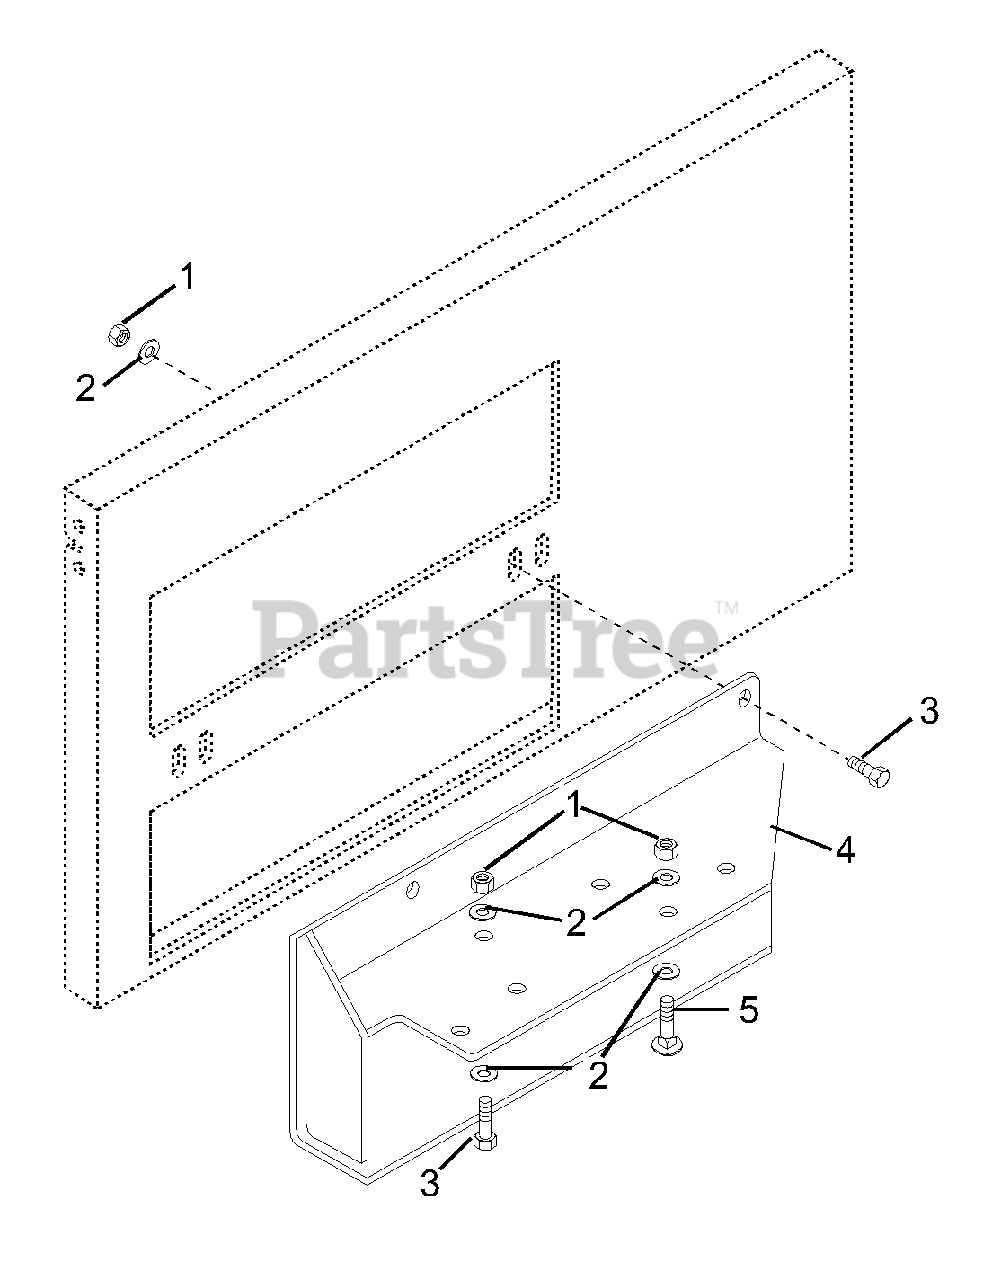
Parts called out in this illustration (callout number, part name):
1	Nut-Locking-Nylon .375-16 Grade 2
2	Washer-Flat-Steel .406 x .812 x .065
3	Bolt-Hex .38-16 x 1.00 Grade 5
4	Weldment-Chute Adapter
5	Bolt-Round Head Square Neck .38-16 x 1.0
